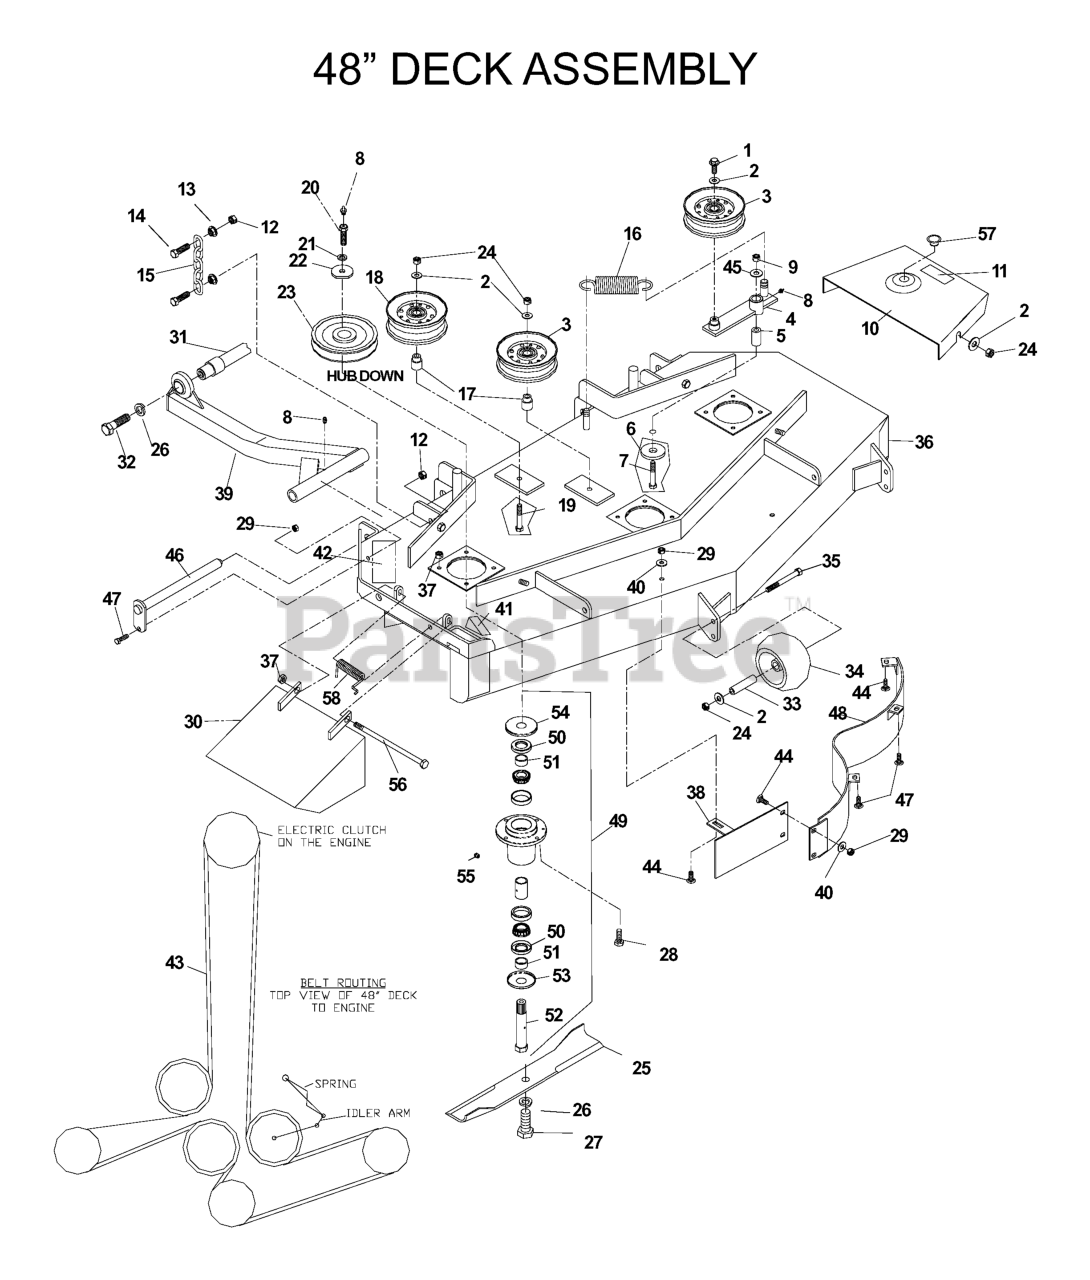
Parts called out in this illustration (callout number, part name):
1	4CS 3/8C X 1 SERRATED HEAD
2	WASHER 3/8 FLAT
3	IDLER PULLEY
5	PIVOT BUSHING
6	WASHER, SUPPORT
7	HCS 1/2C X 3 1/4
8	ZERK
9	NUT 1/2-13 HEX NYLOC ZD
10	LT CE 48 SHIELD, ORANGE
11	DECAL, NO STEP
12	NUT 7/16C CENTERLOCK
13	NUT 7/16C WHIZ
14	HCS 7/16C X 1 1/2
15	LIFT CHAIN
17	IDLER BUSHING
18	IDLER PULLEY (TALL)
19	SCREW 3/8C X 2 3/4 HEX CAP
20	DRILLED BOLT 7/16-20 X 1 1/2"
21	WASHER 7/16 LOCK
22	SPINDLE WASHER
23	RP PULLEY - 42/48"
24	NUT 3/8-16 NYLOC
25	BLADE OEM 16 1/4"
26	LOCKWASHER 5/8
27	HCS 5/8F X 1 1/4
28	HCS 5/16C X 1 1/4
29	NUT 5/16C CENTERLOCK
30	CHUTE 48"
31	STRUT MOUNT WELDMENT
32	HCS 5/8C X 2 GR.5
34	ANTI-SCALP ROLLER
35	HCS 3/8C X 3 1/2
36	DECK W/DECALS 48"
37	NUT 5/16 NYLOC
38	CENTER BAFFLE 48"
39	STRUT, RIGHT
40	WASHER 5/16 FLAT
41	DECAL, CPSC
42	DECAL, DANGER
43	DECK BELT 48"
44	CARRIAGE BOLT 5/16C X 5/8"
45	WASHER 1/2 FLAT
47	HCS 5/16C X 3/4
48	MAIN BAFFLE - 48" DECK BLK
49	SPINDLE
50	SHAFT SEAL
52	SPLINED SHAFT - 42/48"
53	BOTTOM DUST CAP
54	TOP DUST CAP
55	PLUG-VENTED
56	BOLT - 5/16 X 7
57	PLUG, BUTTON HOLE
58	SPRING, TORTION
539108351	STRUT, LEFT
539108925	RT CE 48 SHIELD, ORANGE
